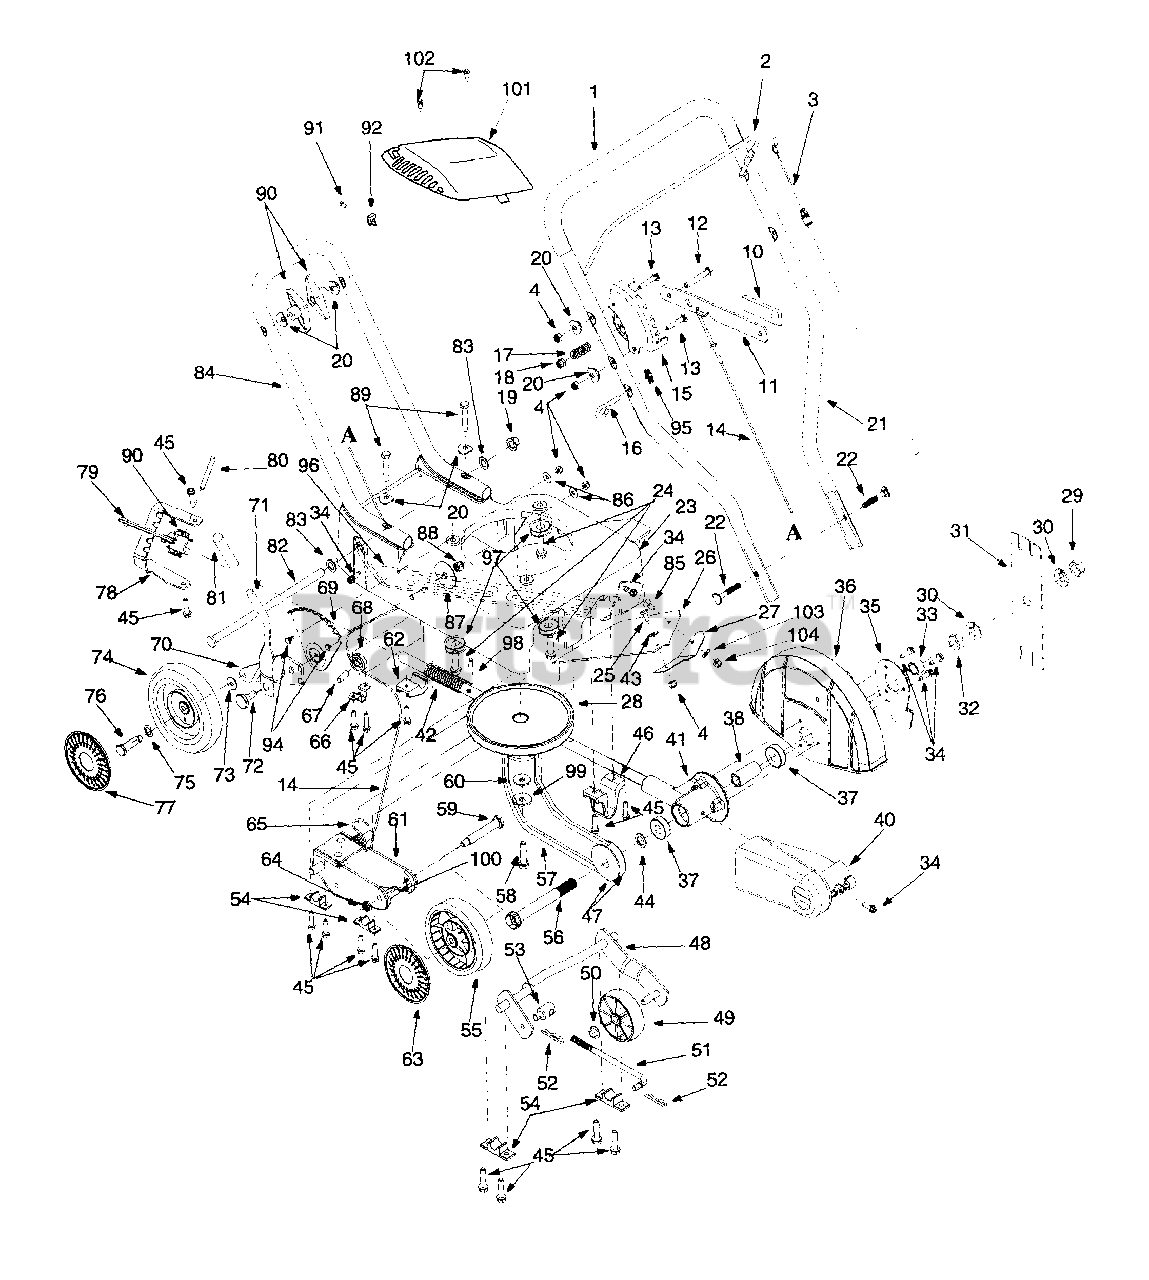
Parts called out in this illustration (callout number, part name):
1	Foam Grip
3	Control Cable 34" B&S
4	Hex Lock Nut 1/4-20
10	Depth Lever Grip
12	Hex Screw 5/16-18 x 2.0 Lg.
13	Thrust Screw 1/4-20 x 1.5
14	Depth Cable
15	Depth Bracket
16	Eye Bolt 1/4-20
17	Compression Spring .550 O.D. x 1.3
18	Hex Lock Nut 5/16-18
19	Push Cap
20	Washer .320 ID x .93 O.D.
23	Edger Base Ass'y
24	Tapp Screw w/Hex Lock Wash 3/8-16
25	Hex Screw 1/4-20 x .50 Lg.
26	Discharge Shield Deflector
27	Deflector Keeper
28	Engine Pulley
29	Hex Jam Nut 5/8-18
30	Bell Washer .63 I.D. x 1.25 O.D. x .18
32	Hex Jam Nut 5/8-18
33	Spacer .628 x .875 x .545 Lg.
34	Hx Scr. w/Wash.: TT: 1/4-20 x .750 Lg.
37	Ball Bearing .62 I.D. x 1.38 O.D. x .4
38	Spacer .628 x .875 x 1.818 Lg.
40	Belt Guard
41	Spindle w/Insert
42	Compression Spring
43	Flat Washer .283 I.D. x .75 O.D. x .030
44	Flat Washer .635 1.D. x .93 O.D. x .06
45	Hex Screw w/Wash 1/4
46	Front Rod Handler
47	Pulley
50	Push Cap
51	Rod 5/16-24
52	Cotter Pin .072 x 1.12
53	Ferrule 5/16-24 x .312
54	Black Bushing .515 Dia x .62
55	Wheel 7 x 2
56	Hex Bolt 5/8-18 x 5.25 Lg.
57	V-Belt
58	Hex Screw: 3/8-24 x 1.50 Lg.
59	Shoulder Screw .500 x 2.62: 3/8-16
60	Flat Washer .38 OD x 1.38 OD
61	Front Wheel Brkt Ass'y.
62	Rear Rod Handler
63	Hubcap: Spoke w/Hole Yellow
64	Jam Lock Nut 3/8-16
65	Torsion Spring
68	Cable Roller Pulley
69	Index Plate
70	Pivot Arm
71	Spring Lever
72	Shoulder Bolt .500 x .434 Lg.
73	Bell Wash..401 ID. x .870 OD. x .063
74	Wheel 8 x 2
75	Wave Washer .510 I.D. x .750 O.D.
76	Shoulder Bolt .498 x 1.445: 3/8-16
77	Hubcap: Radial Spoke Yellow
78	Tilt Bracket
79	Adj. Lever Ass'y
80	Pin 1/4 x 2.0" Lg.
81	Foam Grip
82	Curb Axle
83	Flat Wash. .531 I.D. x .875 O.D. x .06
86	Flat Wash..285 ID x 1.25 OD x .06
87	Flat Wash..406 ID x 1.92 OD x .06
88	Hex Lock Nut 3/8-16
89	Hex Screw 5/16-18 x 1.75 Lg.
90	Torsion Spring
90	Wing Knob Nut 5/16-18
91	Hex Scr. w/Wash.:T: #10-32 x .625 Lg.
92	Clamp B&S Throttle
94	Screw Std. 1/4-20 x .75 Lg.
95	Handle Knob
98	Roll Pin
99	Bell Washer .396 ID x 1.14 OD
100	Spacer .520 ID x .860 Lg.
101	Engine Shroud
102	Hex Washer Screw
103	Lock Washer 1/4
104	Hex Nut 1/4-20
